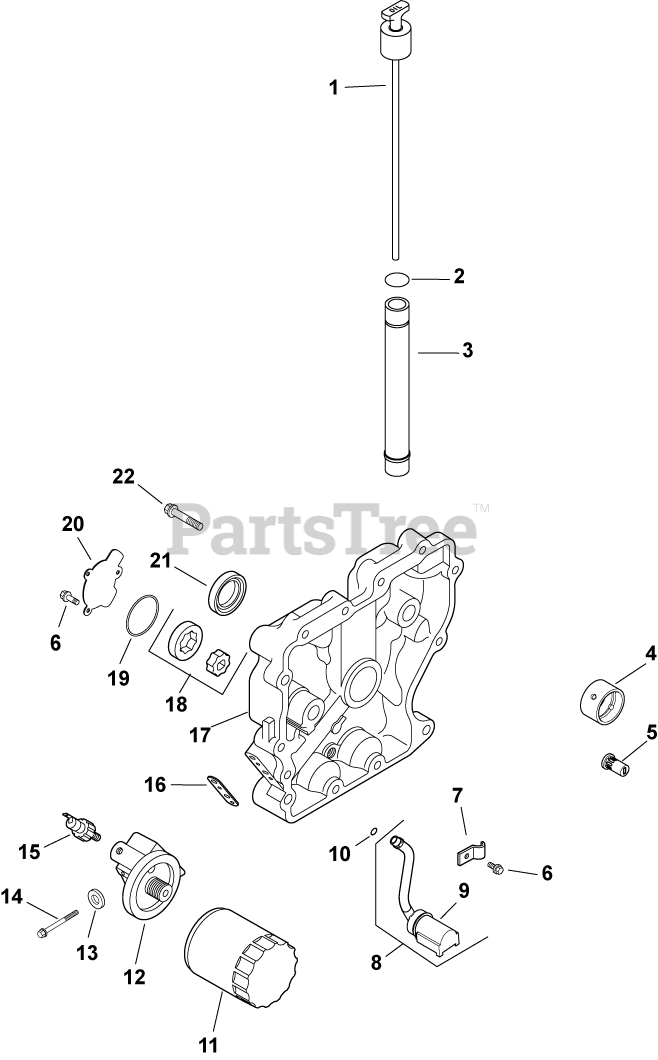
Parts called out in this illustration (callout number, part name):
3	KIT, OIL FILL TUBE - METAL
4	BEARING, CRANKSHAFT
5	VALVE, OIL PRESSURE RELIEF
6	SCREW,FLG THD FRM M5X0.8X16-(#25086398S)
8	KIT, OIL PICK-UP
9	PICK-UP, OIL SCREEN
10	O-RING (.5" DIA)
11	OIL FILTER
12	ADAPTER - DISCONTINUED
14	SCREW, FLG M6X1.0X60
15	SENSOR, OIL PSI
16	GASKET, OIL FILTER ADAPTER
17	CLOSURE PLATE ASSEMBLY - DISCONTINUED
18	PUMP ASSEMBLY, OIL
19	O-RING (1.78" DIA)
20	COVER, OIL PUMP
21	SEAL, OIL
22	SCREW, FLG M8X1.25X45
